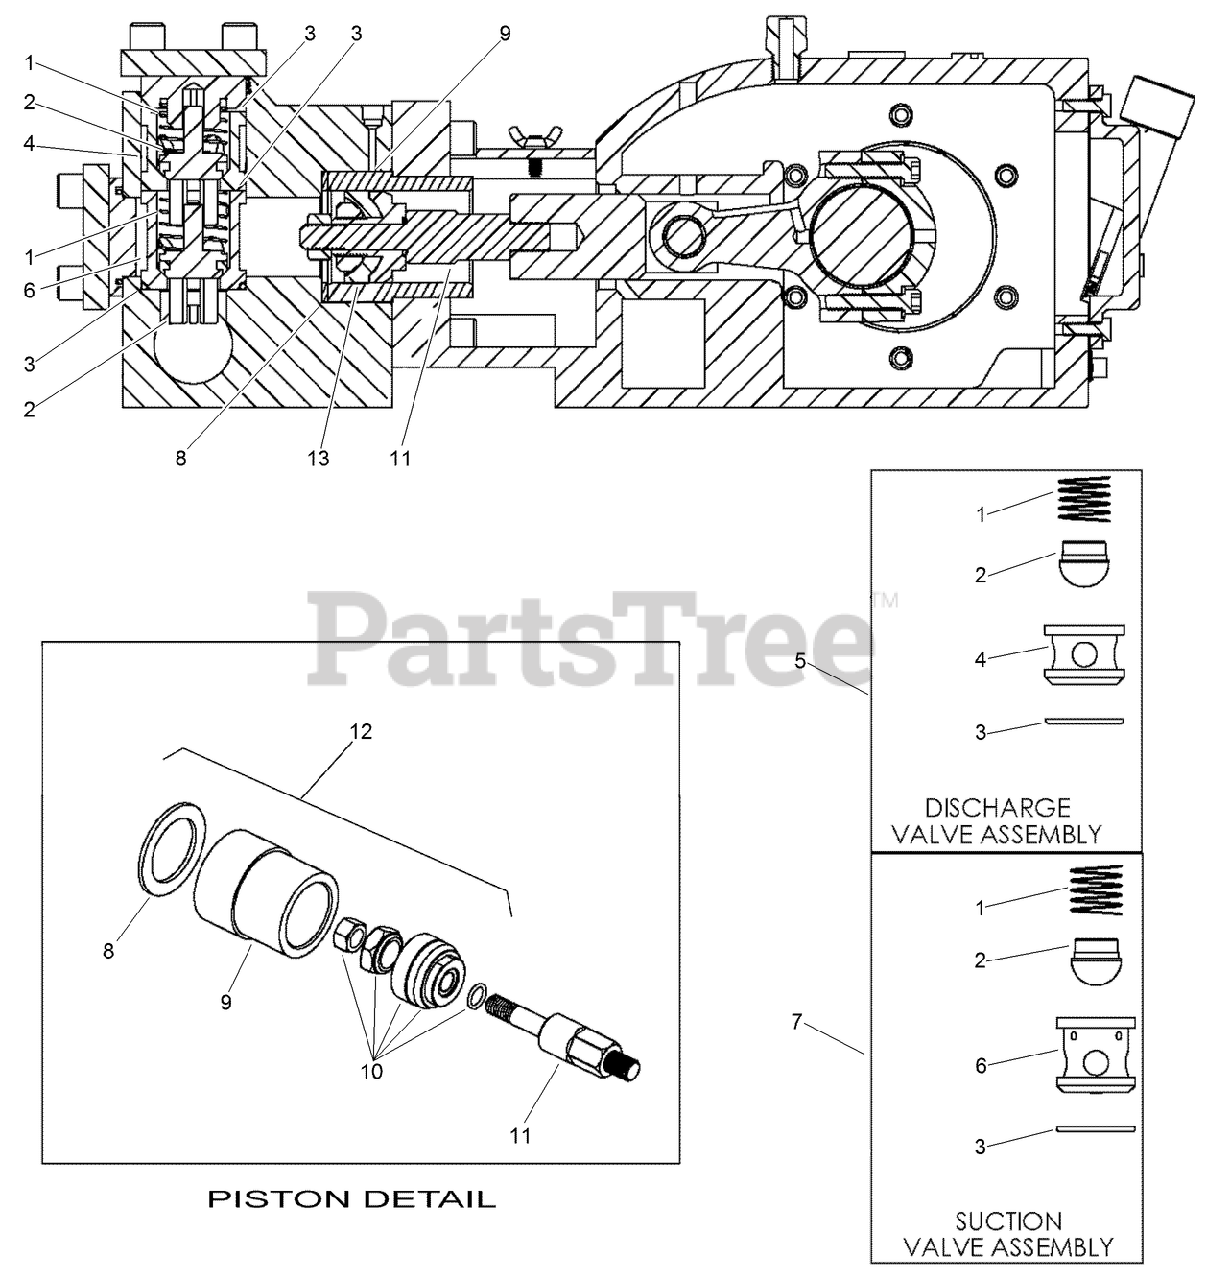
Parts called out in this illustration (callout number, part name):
1	SPRING-VALVE
2	VALVE-BODY
3	O RING-SEAT, VALVE
4	SEAT-VALVE, DISCHARGE
5	DISCHARGE VALVE ASM
6	SEAT-VALVE, SUCTION
7	SUCTION VALVE ASM
8	Liner Gasket
9	LINER-PISTON, CERAMIC
10	HSN PISTON KIT
11	ROD-EXTENSION, PISTON
12	GOLD PISTON KIT
13	CUP-PISTON, GOLD
